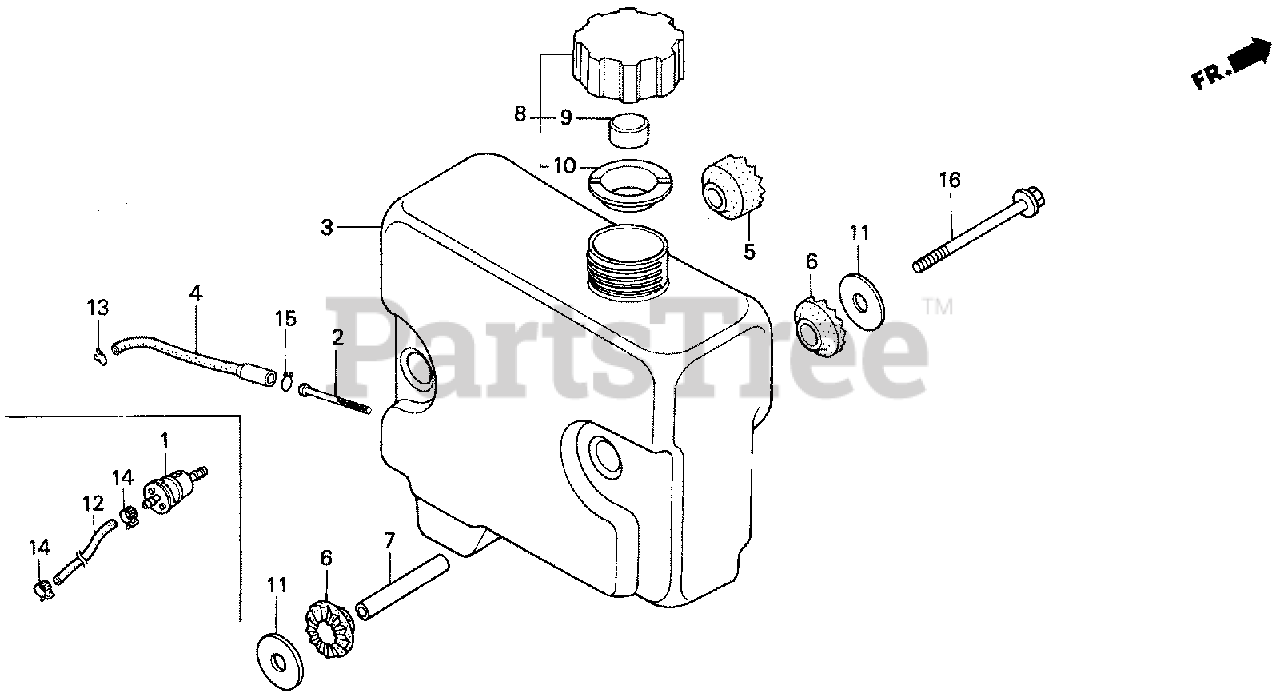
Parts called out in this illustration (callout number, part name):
2	FILTER, FUEL
3	TANK, FUEL
4	TUBE, FUEL
5	RUBBER B, TANK MOUNTING
6	RUBBER B, TANK MOUNTING
7	COLLAR, TANK SETTING
8	CAP ASSY., FUEL TANK
9	SPONGE, FUEL CAP BREATHER
10	GASKET, FUEL CAP
11	WASHER, TANK MOUNTING
13	CLIP, TUBE (B8)
15	CLIP, TUBE (C11)
16	BOLT, FLANGE (8X90)
